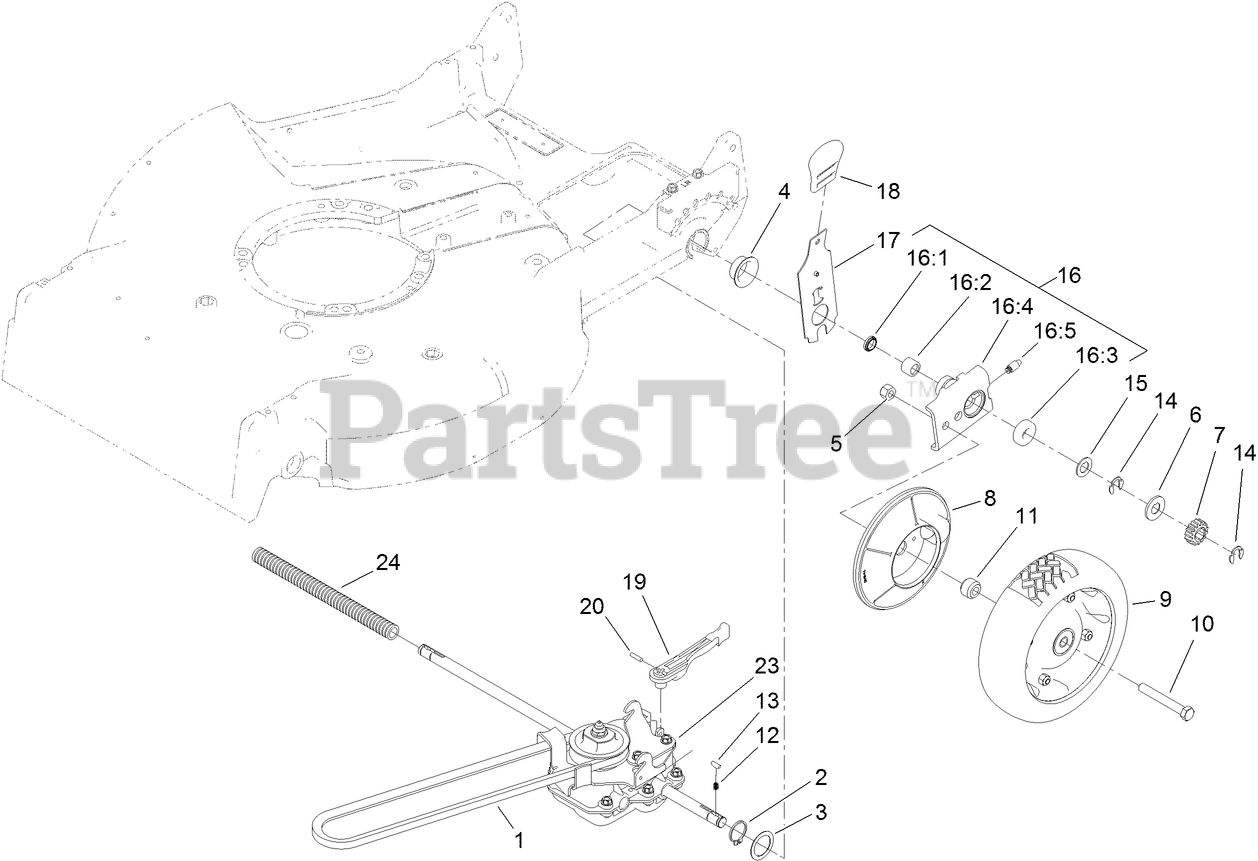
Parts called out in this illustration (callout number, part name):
1	V-BELT
2	RING-RETAINING
3	WASHER
4	CAP-END
5	NUT-LOCK, CONE
6	WASHER-THRUST, OUTER
7	GEAR-PINION
8	COVER-WHEEL
9	WHEEL AND TIRE ASM
10	SCREW-HH
11	SPACER-COVER, WHEEL
12	SPRING-COMPRESSION
14	RING-RETAINING
15	WASHER-THRUST, OUTER
16	PIVOT ARM ASM
16:1	SEAL-OIL
16:2	BEARING-CAGED NEEDLE ROLLER
16:3	BEARING-WHEEL
16:4	Arm-Pivot, Rear
17	REAR SPRING ARM ASM
18	KNOB-HOC
19	LEVER-SHIFT
20	PIN-SPRING
23	GEAR CASE ASM
24	COVER-SHAFT, DRIVE
